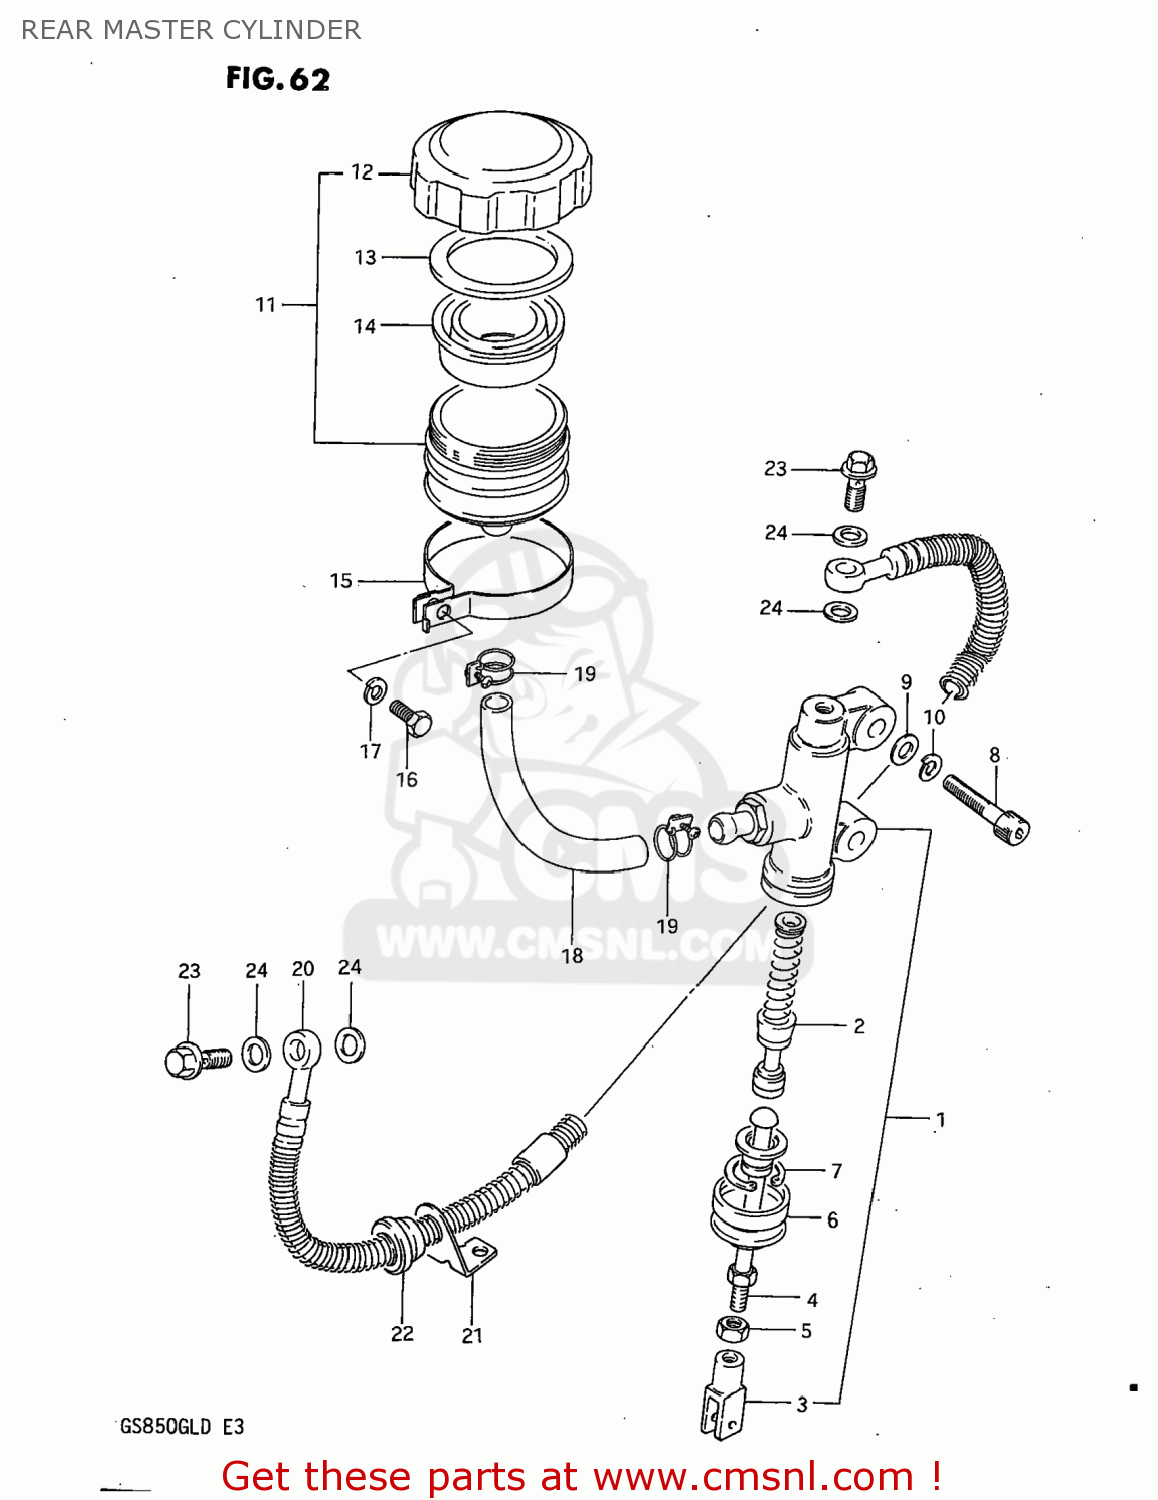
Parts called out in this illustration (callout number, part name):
1	CYLINDER ASSY,RR MASTER
2	PISTON/CUP SET
3	YOKE
4	ROD,REAR MASTER CYLINDER
5	NUT,MASTER CYLINDER
6	BOOT
7	CIRCLIP
8	BOLT
9	WASHER
10	WASHER,LOCK,8.
11	TANK ASSEMBLY,RESERVOIR
12	CAP
13	PLATE,DIAPHRAGM
14	DIAPHRAGM
15	CLAMP
16	BOLT, UPPER
17	LOCK WASHER
18	HOSE,RESERVOIR TANK
19	CLAMP
20	HOSE,REAR BRAKE
21	GUIDE,BRAKE HOSE
22	GROMMET,BRAKE HOSE GUIDE
23	BOLT,UNION
24	WASHER
